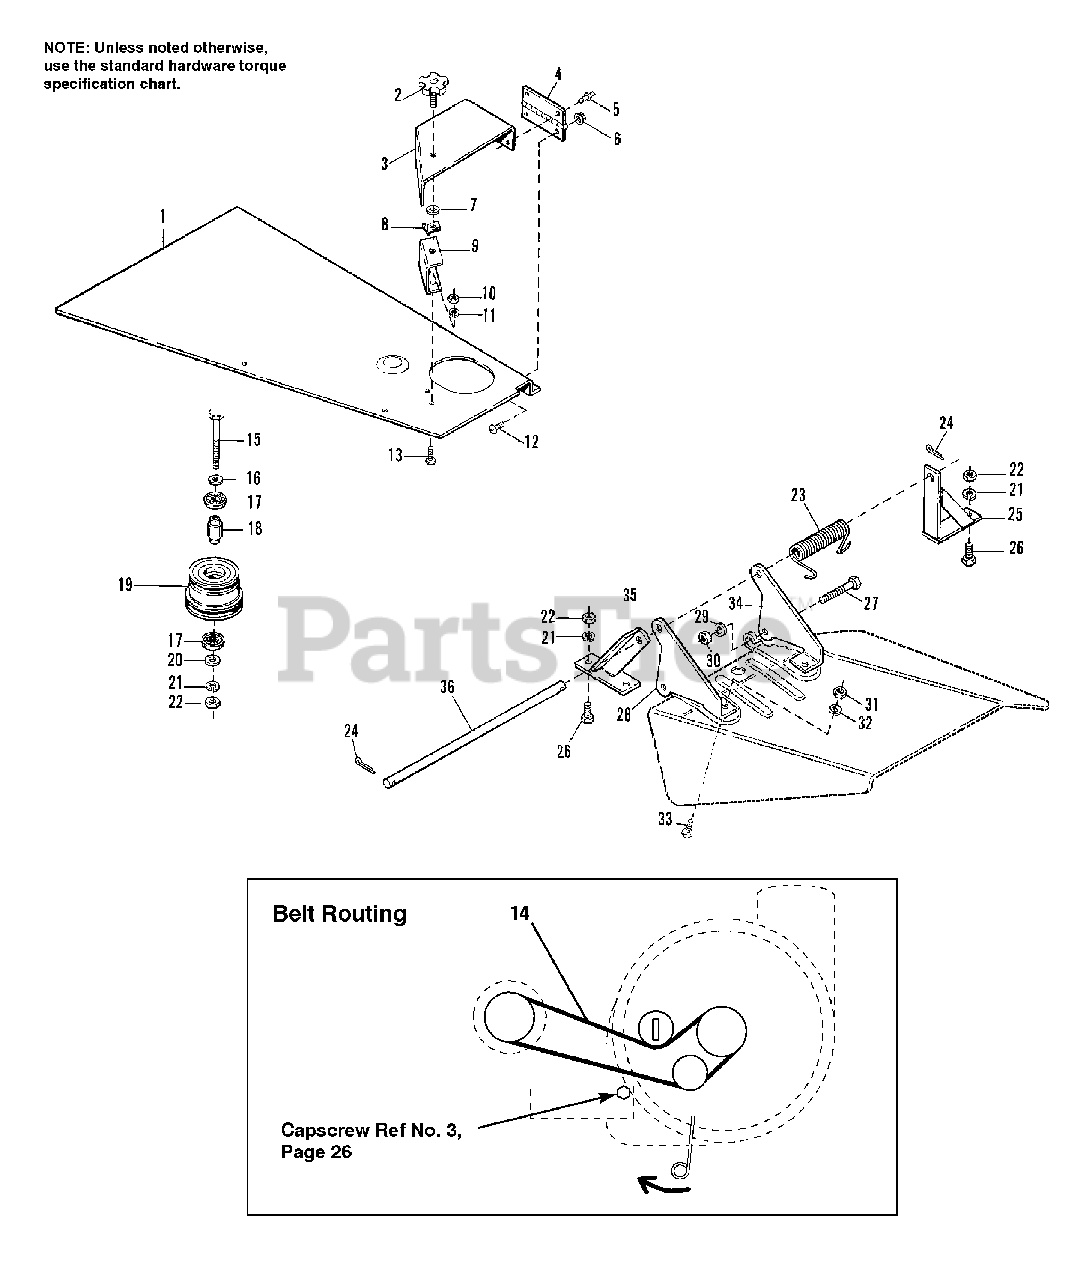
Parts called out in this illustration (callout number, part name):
1	COVER, LH Mower
2	KNOB, Plastic
3	COVER ASSEMBLY
5	POP-RIVET, 3/16 x 5/16
6	NUT, Hex Flange, #10-32
7	NUT, Push, 5/16
8	NUT, Speed, 5/16-18
9	BRACKET, Belt Cover
10	NUT, Hex, 1/4-20
11	WASHER, Lock, 1/4
12	SCREW, Rd Hd Machine, #10-32 x 3/8
13	CAPSCREW, Hex Hd, 1/4-20 x 1/2
14	V-BELT
15	CAPSCREW, Hex Hd, 3/8-16 x 3-1/4
16	WASHER, 3/8
18	SPACER, Pulley
21	WASHER, Lock, 3/8
22	NUT, Hex, 3/8-16
23	SPRING, Torsion
24	PIN, Cotter, 3/32 x 3/4
25	HINGE ASSEMBLY, Rear
26	CAPSCREW, Hex Hd, 3/8-16 x 1
27	CAPSCREW, Hex Hd, 7/16-14 x 2-3/4
28	BRACKET, LH Pivot
29	WASHER, Lock, 7/16
30	NUT, Hex, 7/16-14
31	NUT, Hex, 5/16-18
32	WASHER, Lock, 5/16
33	CAPSCREW, Hex Hd, 5/16-18 x 7/8
34	BRACKET, RH Pivot
35	HINGE ASSEMBLY, Front
